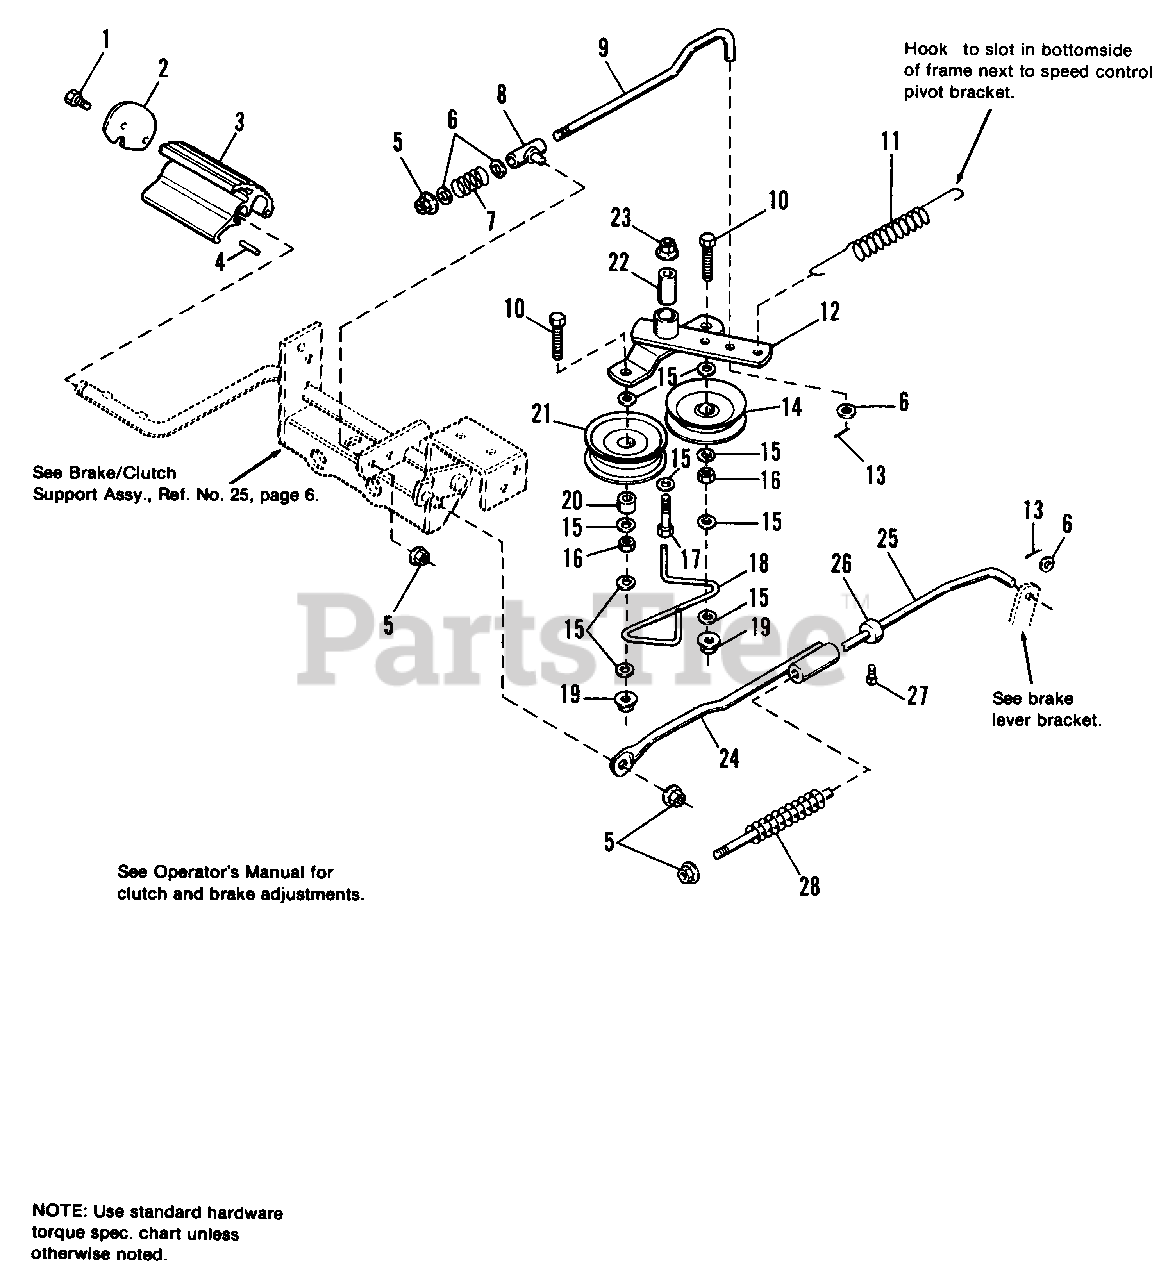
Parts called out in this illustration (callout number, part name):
1	SCREW, Taptite, 1/4-20 x 5/8
2	PLATE, End
3	PEDAL, Brake
4	DAMPER, Rubber
5	NUT, Flange Lock, 5/16-18
7	SPRING, Compression
8	GUIDE ASSY., Rod
9	ROD, Clutch
10	CAPSCREW, 3/8-16 x 2, Full Thread
11	SPRING, Tension
12	BRACKET ASSY., Idler
13	PIN, Cotter
14	PULLEY, V-Idler
15	WASHER
16	NUT, Jam, 3/8-16
17	CAPSCREW, 3/8-16 x 2
18	GUIDE, Belt
19	NUT, Hex, 3/8-16
20	SPACER (For Flat-Side Pulley)
21	PULLEY, Flat-Side
23	NUT, Whiz Flange
24	ROD ASSY., Brake
25	ROD, Brake
26	COLLAR, Set
27	SET SCREW, Sq. Hd.
28	SPRING, Compression
